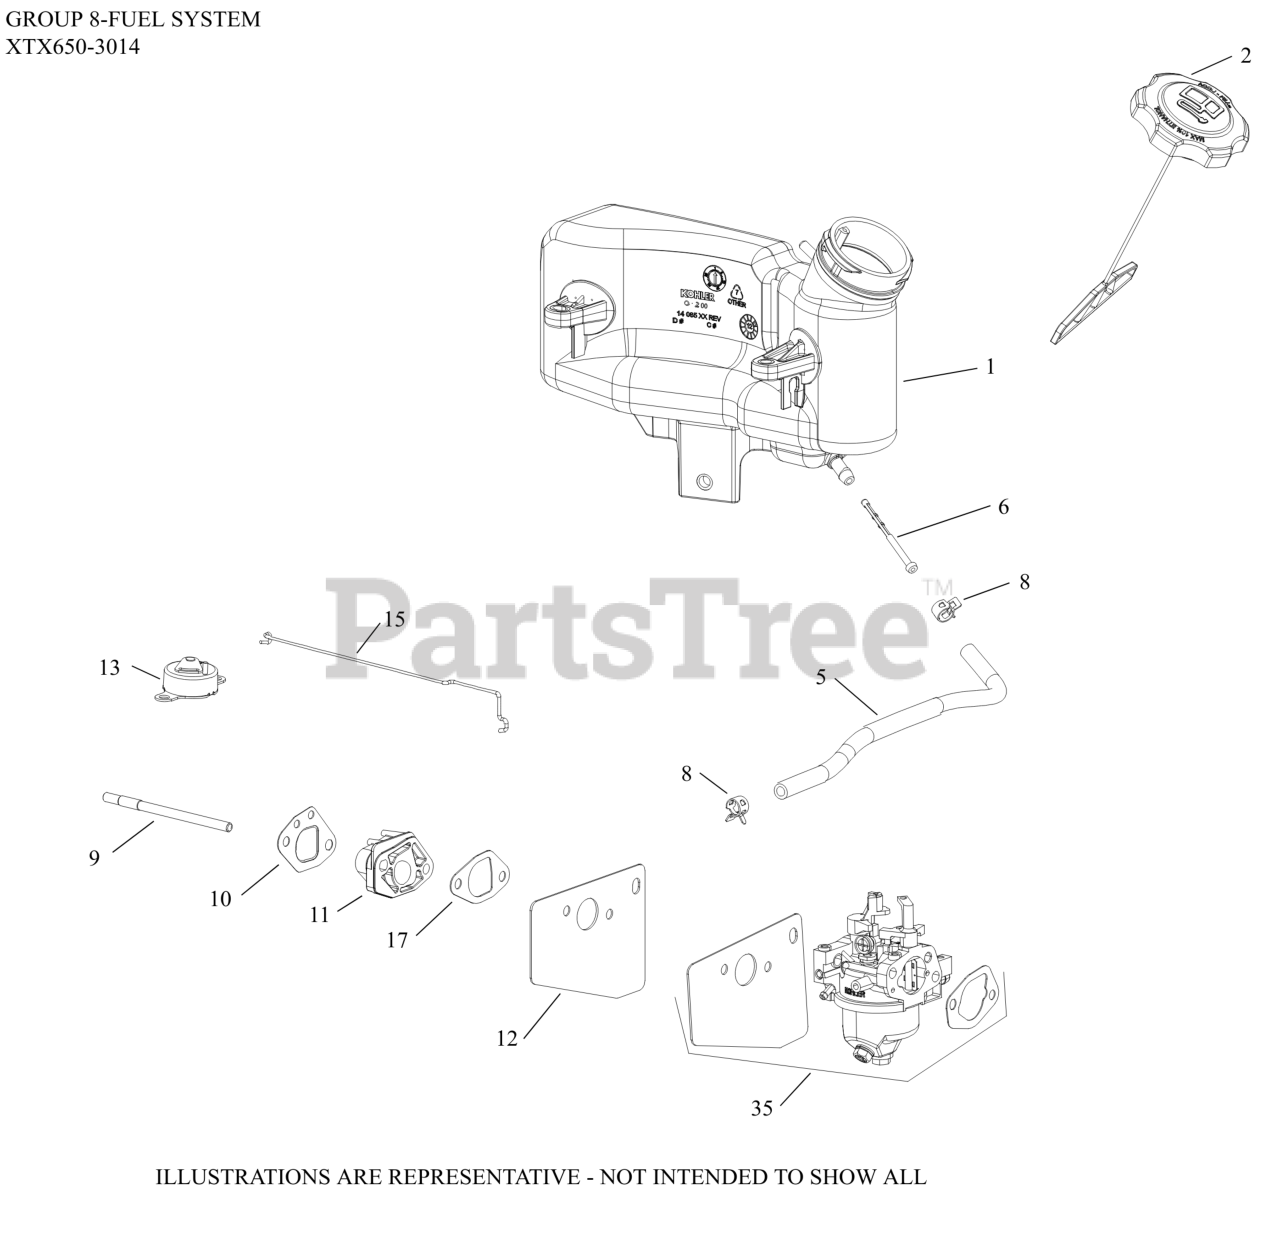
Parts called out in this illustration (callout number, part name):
1	TANK, FUEL
2	FUEL CAP ASSEMBLY
5	HOSE, FUEL LOW-PERMEATION (CKY)
6	FILTER, FUEL IN-NIPPLE
8	CLAMP, HOSE (NON-CALIF)(#1423710S)
9	STUD,M6X1.0X100.2MM
10	GASKET, SPACER - USE 14 041 24-S
11	SPACER, CARBURETOR
12	KIT, CARBURETOR HEAT SHIELD GASKET
13	ARM ASSEMBLY, AUTO CHOKE
15	LINKAGE, AUTO CHOKE
17	KIT, INTAKE GASKET
35	KIT, CARBURETOR COMPLETE
NI	KIT, HIGH ALTITUDE (4,000-8,000 FT)
NI	KIT, CARBURETOR REPAIR (RUIXING)
